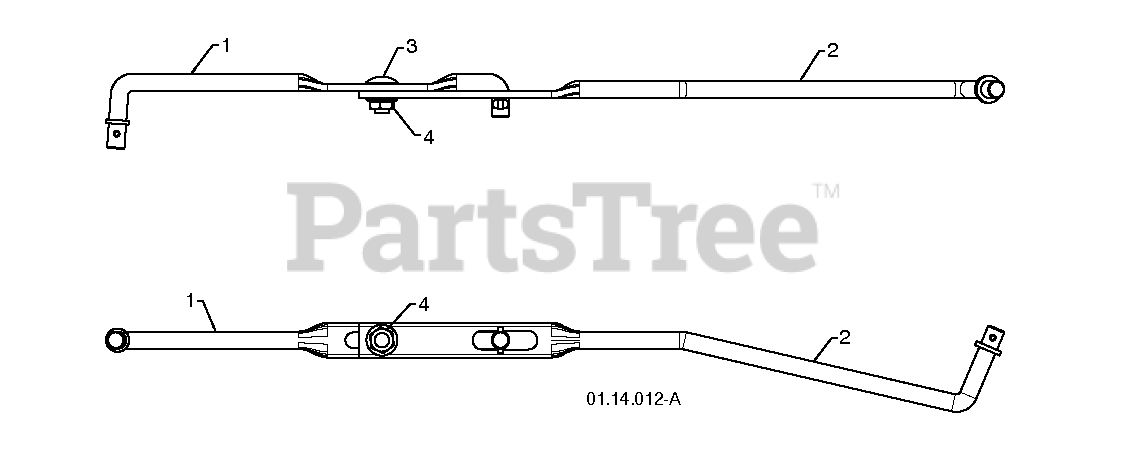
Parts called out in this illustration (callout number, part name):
1	ROD.SHIFTER.TOP.HYD
2	ROD, LOWER, SPEED CONTROL
3	BOLT
4	NUT.FLANGE.5/16
